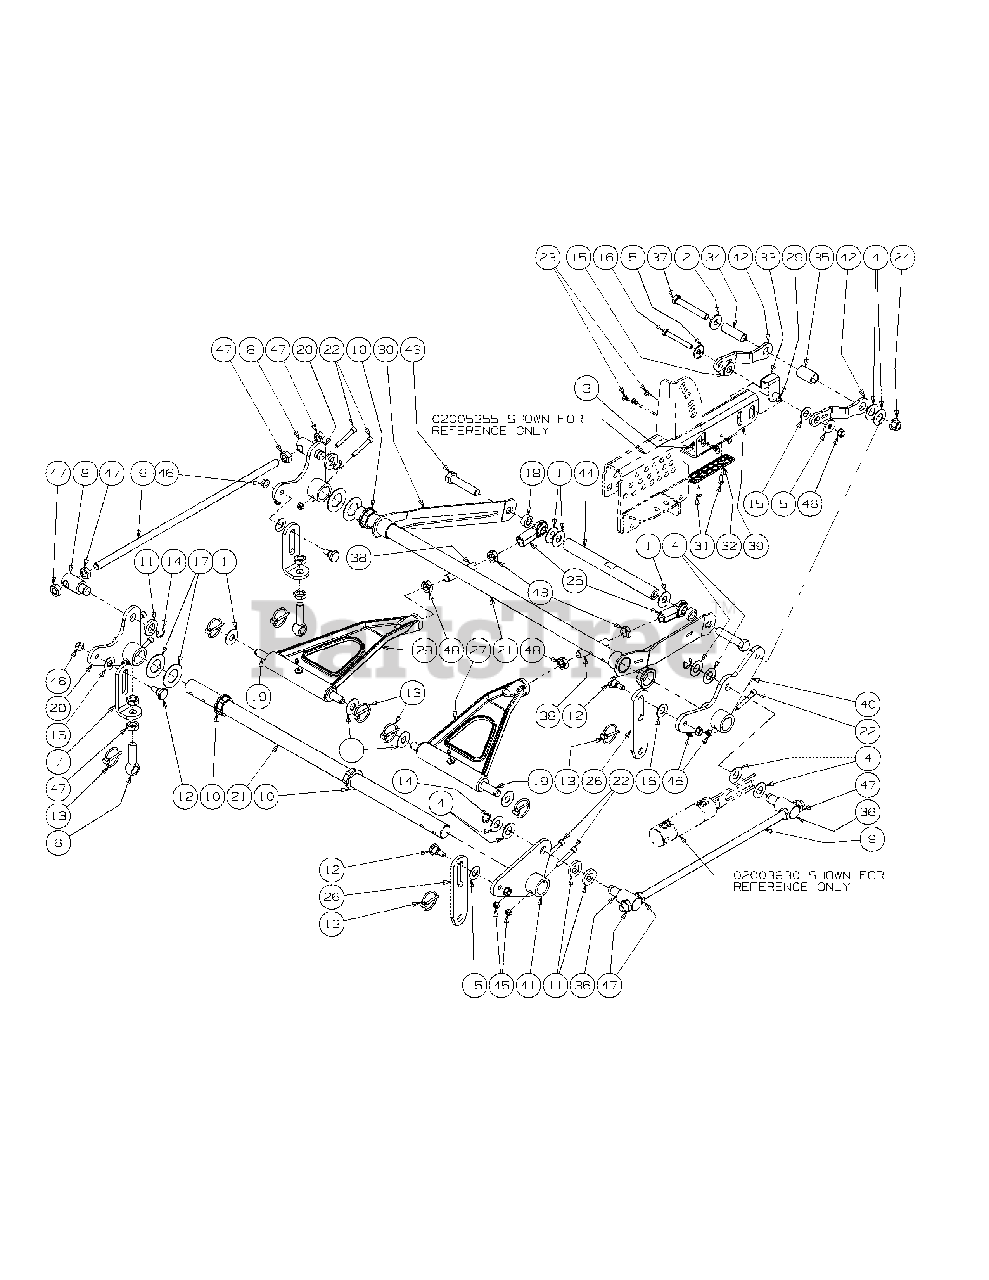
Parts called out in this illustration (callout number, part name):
1	Washer, 1.5 x .655 x .055
2	Flat Washer, 1/2
3	Lock Nut w/Nylon Insert
4	Washer, .76 x 1.49 x .06
5	Flat Washer, 1.25 x .411 x .100
6	Eye Bolt, 5/8ID
7	Eye Bolt Mount Link, 5/8 ID
8	Ferule Lift
9	Lift Connector Rod
10	Hex Flange Bearing, 1.25 ID
11	Spacer, .812 ID x .268 Lg.
12	Shoulder Screw, 0.625 OD x .437 Lg.
13	Linch Pin, 3/16 Dia.
14	E Clip, 3/4 Dia.
15	Nylon Flat Washer, 5/8
16	HHCS, 3/8-16, 3.00
17	Flat Washer, 1.25 ID
18	Spacer, .630 ID x 1.06 OD x .440
19	Lift Link Rod
20	Bellecrank Weldment Assembly
21	Deck Lift Shaft
22	Socket Head CapScrew, 5/16-18 x 2
23	Rivet, 1/4 x 5/8
24	Nut, 1/2-13, FlangeLock
25	Rod End, 5/8, RH
27	Bearing Lift Brace Assembly, Left Hand includes:
28	Bearing Lift Brace Assembly, Right Hand includes:
29	Spacer, .375 ID x .625 OD x 2.20
30	Front Frame Strut Assembly
31	Flat Head Cap Screw, 1/4-20 x .75
32	Lift Wear Plate
34	Spacer, .51 ID x .75 OD x 2.38
35	Spacer, .765 ID x 1.0 OD x 1.70
36	Ferule Lift, 1.938
37	HHCS, 1/2-13 x 3.50
38	Rod, 5/8-18 x 3.50
39	Lift Tube, 3.0 x 1.5
40	Bellecrank Hydraulic Assist Assembly
41	Bellecrank Weldment Assembly
42	Offset Lift Yoke Bracket
43	HHCS, 5/8-11 x 3.00
44	Front Lift Link Shaft, Threaded
45	Nut, 5/16-18, Nylock
46	Hex Nut, Flange Lock, 3/8-16
47	Jam Nut, 5/8-11
48	Jam Nut, 5/8-18
